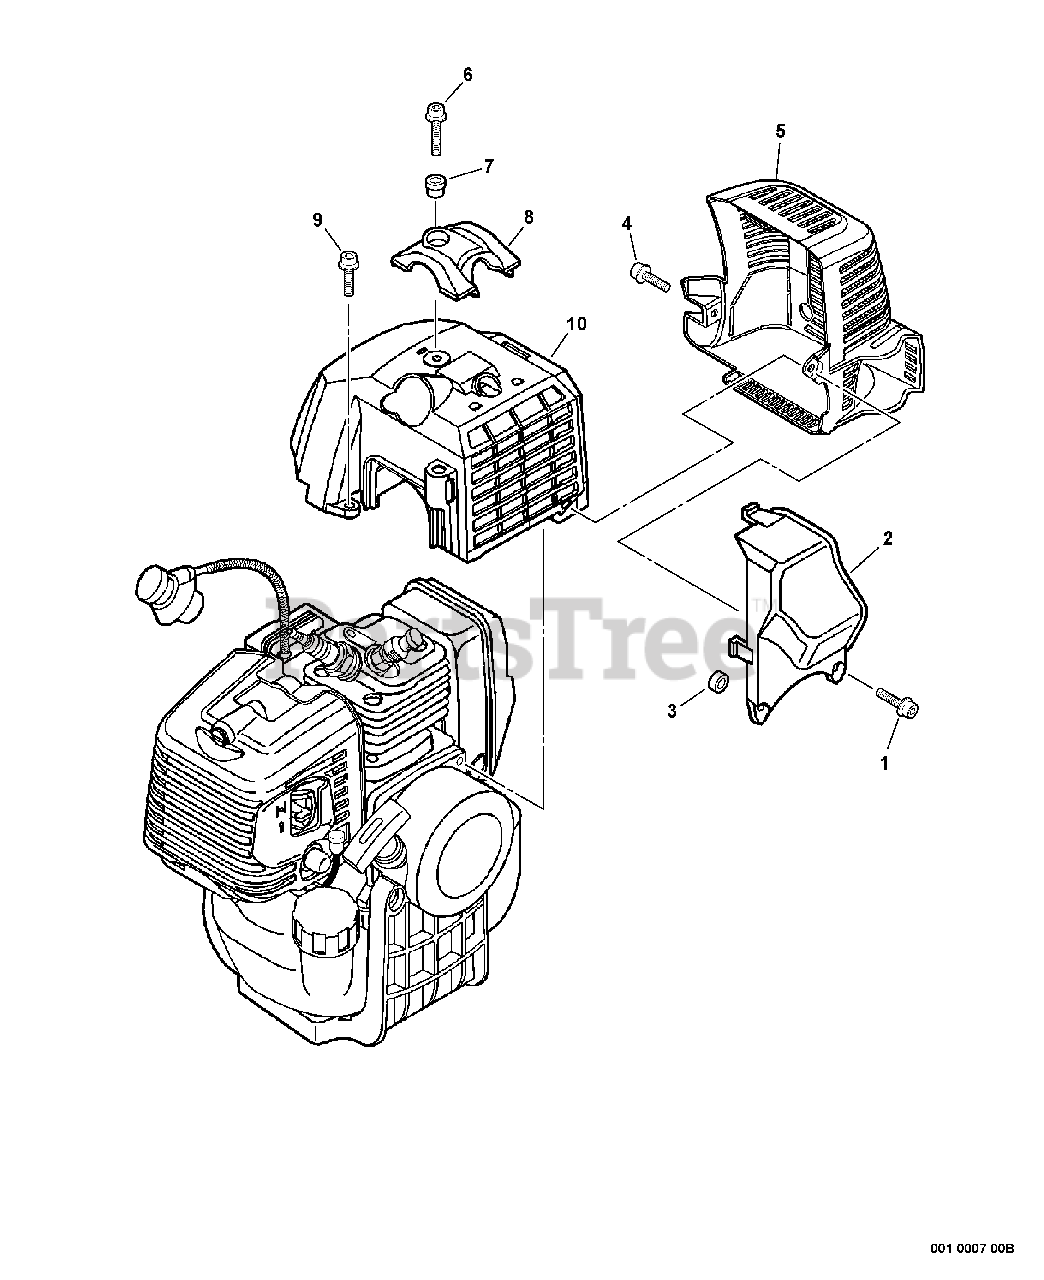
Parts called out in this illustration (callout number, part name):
1	SCREW - 5X25
2	DEFLECTOR, EXHAUST
4	SCREW - 5X12
5	COVER, EXHAUST
6	SCREW - 5X20
7	COLLAR - 5
8	GUARD - TOP
9	SCREW - 5X12
10	COVER, ENGINE - ORANGE
